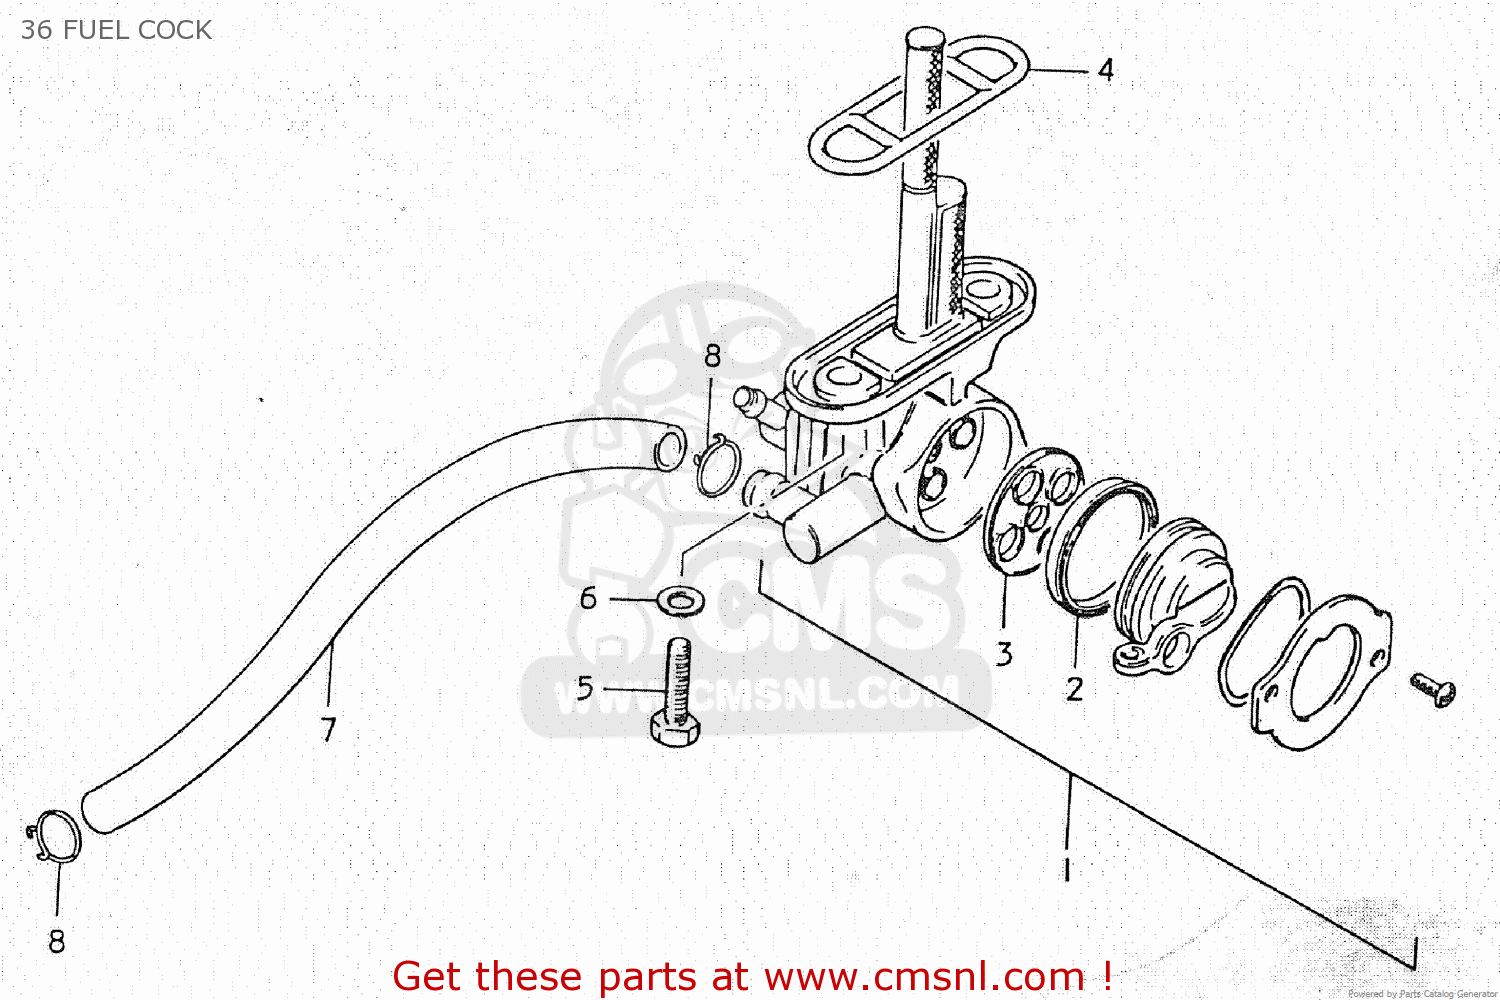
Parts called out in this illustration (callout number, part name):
1	COCK ASSEMBLY,FUEL
2	V SEAL,FUEL COCK
3	GASKET (NAS)
4	GASKET,FUEL COCK (NAS)
5	BOLT(6X20)
6	GASKET
7	HOSE
8	CLIP
